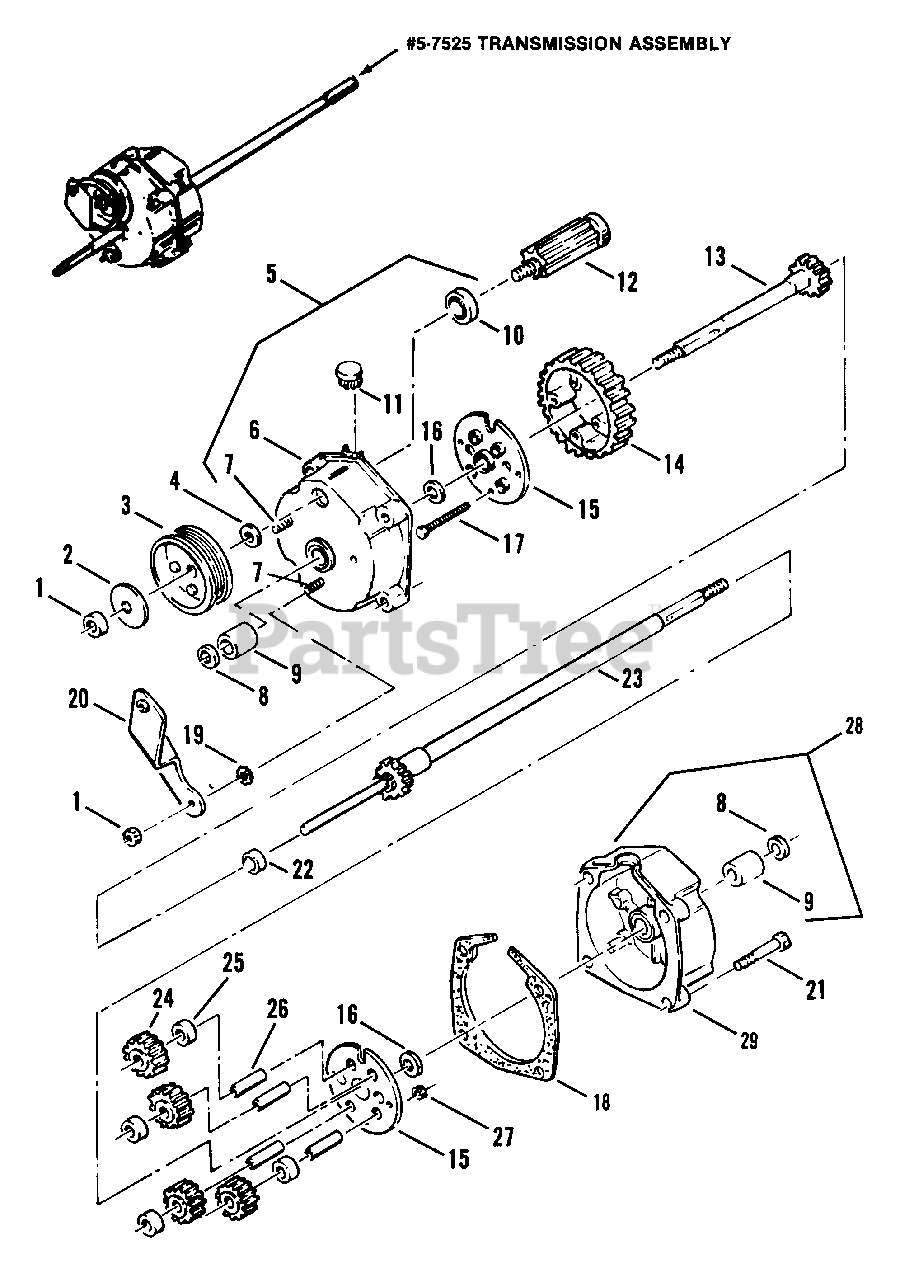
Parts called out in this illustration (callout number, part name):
1	NUT, 5/16-24 Hex Lock, GR C
2	WASHER, Spring
3	PULLEY, Poly-Vee Belt
4	WASHER, Spring
5	HOUSING ASSEMBLY, Right
5-7525	ASSEMBLY, Transmission
6	HOUSING, Right Side
7	SCREW, 5/16-24x1-1/8" Rib Neck
8	SEAL, 5/8" ID
9	BEARING, Differential
10	BEARING, Ball
11	PLUG, Housing
12	GEAR, Input
13	AXLE, Short
14	GEAR, Differential, 46 Tooth
15	PLATE
16	WASHER, Thrust
17	SCREW, Cap, 10-32x1-1/2
18	GASKET, Housing
19	WASHER, 5/16" Internal External Tooth Lock
20	BRACKET, Differential
21	SCREW, 1/4-20x1-1/4 Self-Tapping
22	SPACER, Axle Gear
23	AXLE, Long
24	GEAR, Pinion, 12 Tooth
25	SPACER, Pinion Gear
26	SHAFT, Pinion
27	LOCKNUT, 10-32
28	HOUSING ASSEMBLY, Left
29	HOUSING, Left Side
